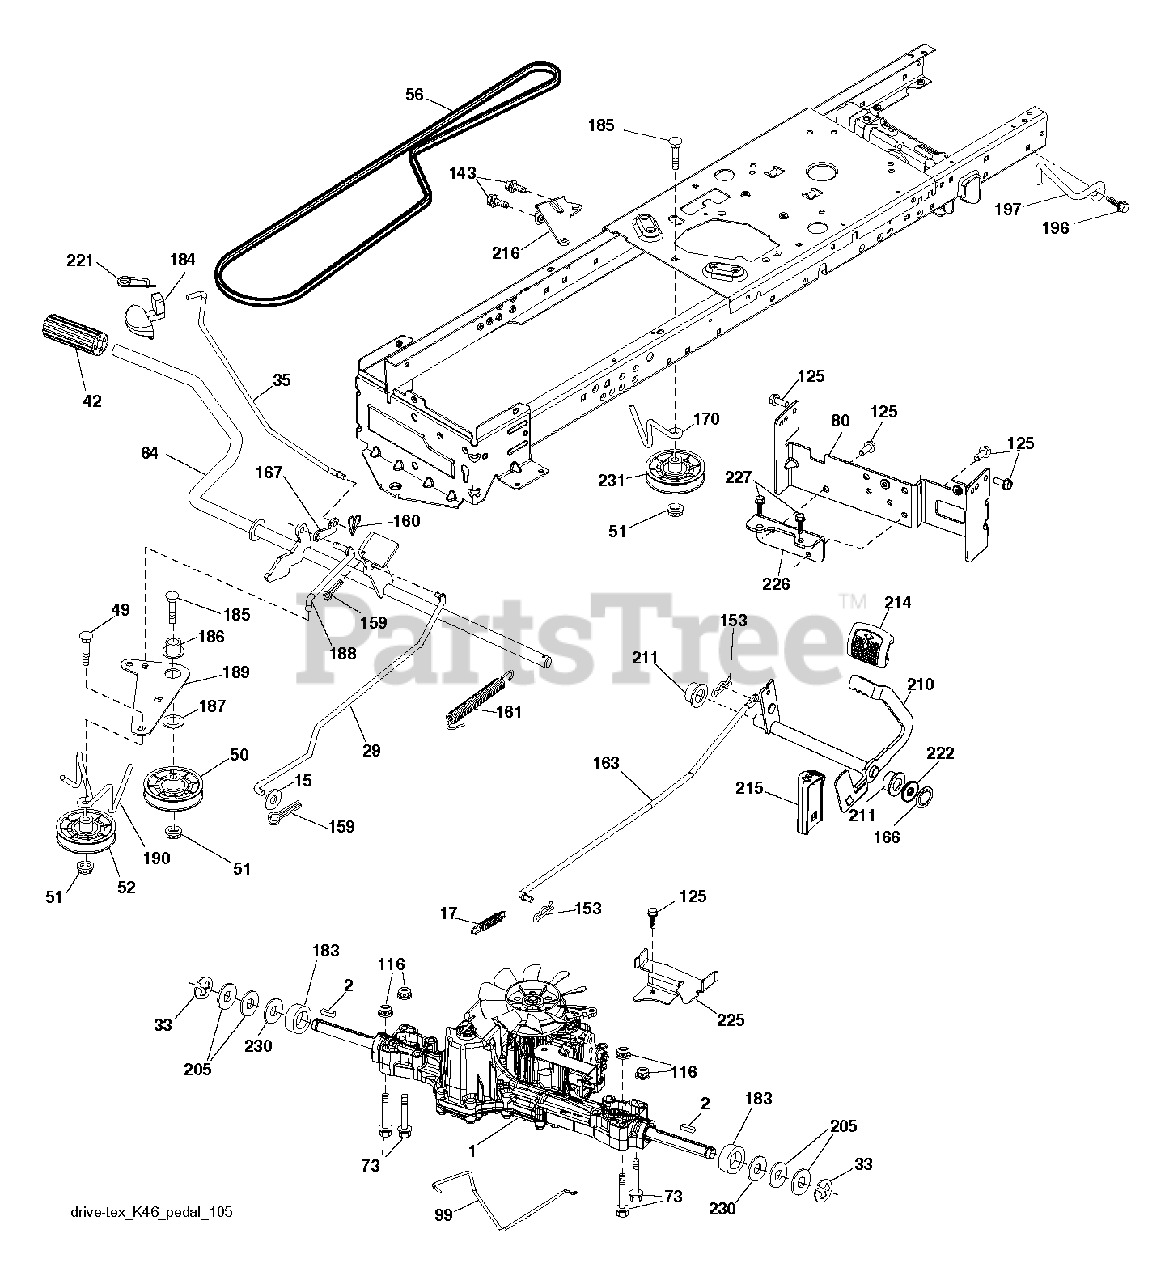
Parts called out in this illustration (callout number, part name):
2	SQUARE KEY
15	WASHER
17	SPRING.BRAKE.K46.GREEN
29	ROD.BRAKE.K46
35	ROD.CNTRL.PARK.PREDATOR.LT.TEX
42	PEDAL COVER T
50	IDLER.FLAT.910.OFFSET
51	NUT LOCK FLG 3/8-16 UNC
52	IDLER.V-GROOVE.910.OFFSET
56	V-BELT.MOWER.92.40.42/K46
64	SHAFT.ASM.PEDAL.BRAKE.
80	STRAP.TORQUE.K46.K57R.TT
99	ROD.SPRING.BYPASS.K46.LT.Z
116	NUT LOCK HEX FLANGE 5/16-18
125	SCREW
143	SCREW LT
153	RETAINER M
159	COTTER PIN
160	RETAINER CLIP
161	SPRING, RETURN LT
163	ROD.CONTROL.PEDAL.K46
166	NUT.PUSH.625
167	LATCH.BRAKE.SPRING
170	KEEPER.CENTER SPAN.1.688
183	SPACER AXLE
184	HANDLE.PARKING.BRK.PRED.LT.RED
186	SPACER.RETAINER
187	WASHER 12/32X2X10GA
188	RP LINK.CLUTCH.GROUND.DRIVE
189	BELLCRANK.GROUND.DRIVE.TEX.
190	KEEPER.BELLCRANK.DRIVE
196	SCREW 3/8-16X1
197	LINK.CLUTCH.ANIT-ROTAT
210	ROCKER.ASM.PEDAL.CONTR
211	BEARING.NYLON
214	PEDAL.FORWARD.PAD.TEX
215	PEDAL.REVERSE.TEX.GT.4
216	BRACKET.PULLEY.IDLER.W/TEX
221	RETAINER.SPRING.CLIP.H
222	WASHER 21/32 X 1-1/4 X 10 GA.
225	KEEPER.BELT.TRANSAXLE.K46
226	BRACKET.MOUNT.TORQUE.K46.TLT
227	SCREW
230	WASHER.HARDENED
231	IDLER.V-GROOVE.1.688.OFFSET
